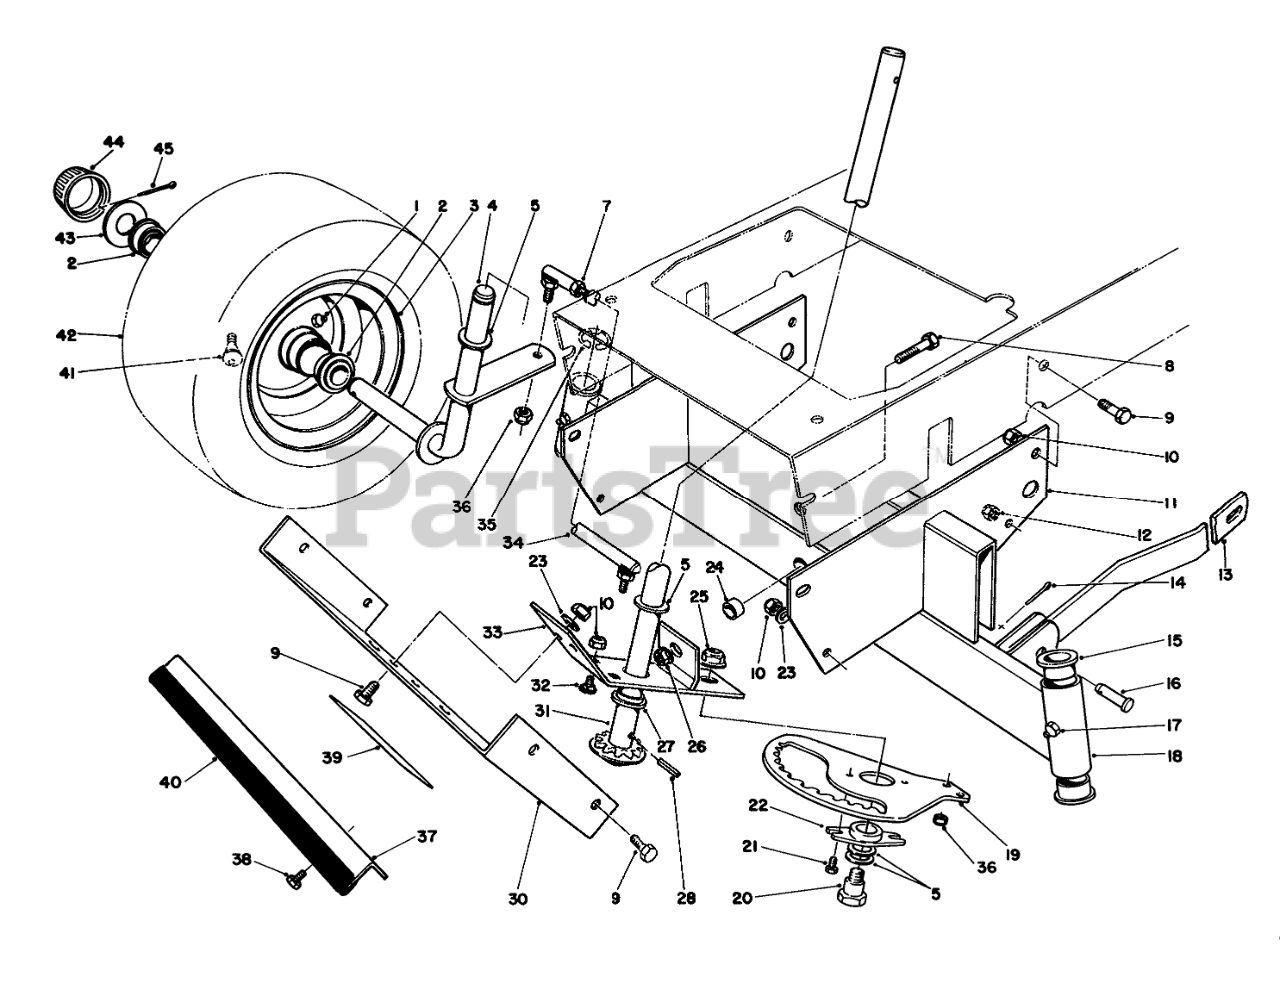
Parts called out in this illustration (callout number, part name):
1	FITTING-GREASE
2	Bearing
4	Spindle RH
5	WASHER-THRUST
7	NUT-JAM
8	SCREW-HH
9	SCREW-HH
10	NUT-LOCK, NI
11	Support
12	NUT-HEX
13	Arm-Suspension, Front
14	PIN-COTTER
15	BEARING-FLANGE
16	PIN-CLEVIS
17	GREASE FITTING
18	Axle-Front (Incl. Ref. #15 & 17)
19	Rack-Steering
21	SCREW-HWH
22	BUSHING-SECTOR
23	WASHER-PLAIN
24	SPACER-AXLE, FRONT
25	NUT-HF
26	NUT-HF
27	BEARING-FLANGE
28	PIN-ROLL, SLOTTED
30	Cover-Front
31	STRG SHAFT WA
32	SCREW-CARR
33	Bracket-Rack, Steering (Incl. Ref. #27)
34	Tie Rod-Adjustable (Incl. Ref. #7)
35	E-RING
36	NUT-LOCK
37	FRONT GUARD R
38	SCREW-HWHTF
39	Decal-Warning
40	TRIM-FRONT GUARD
41	Stem-Valve
42	TIRE,PNEU.11X4.00X5
43	WASHER-PLAIN
44	CAP-HUB
45	PIN-COTTER
